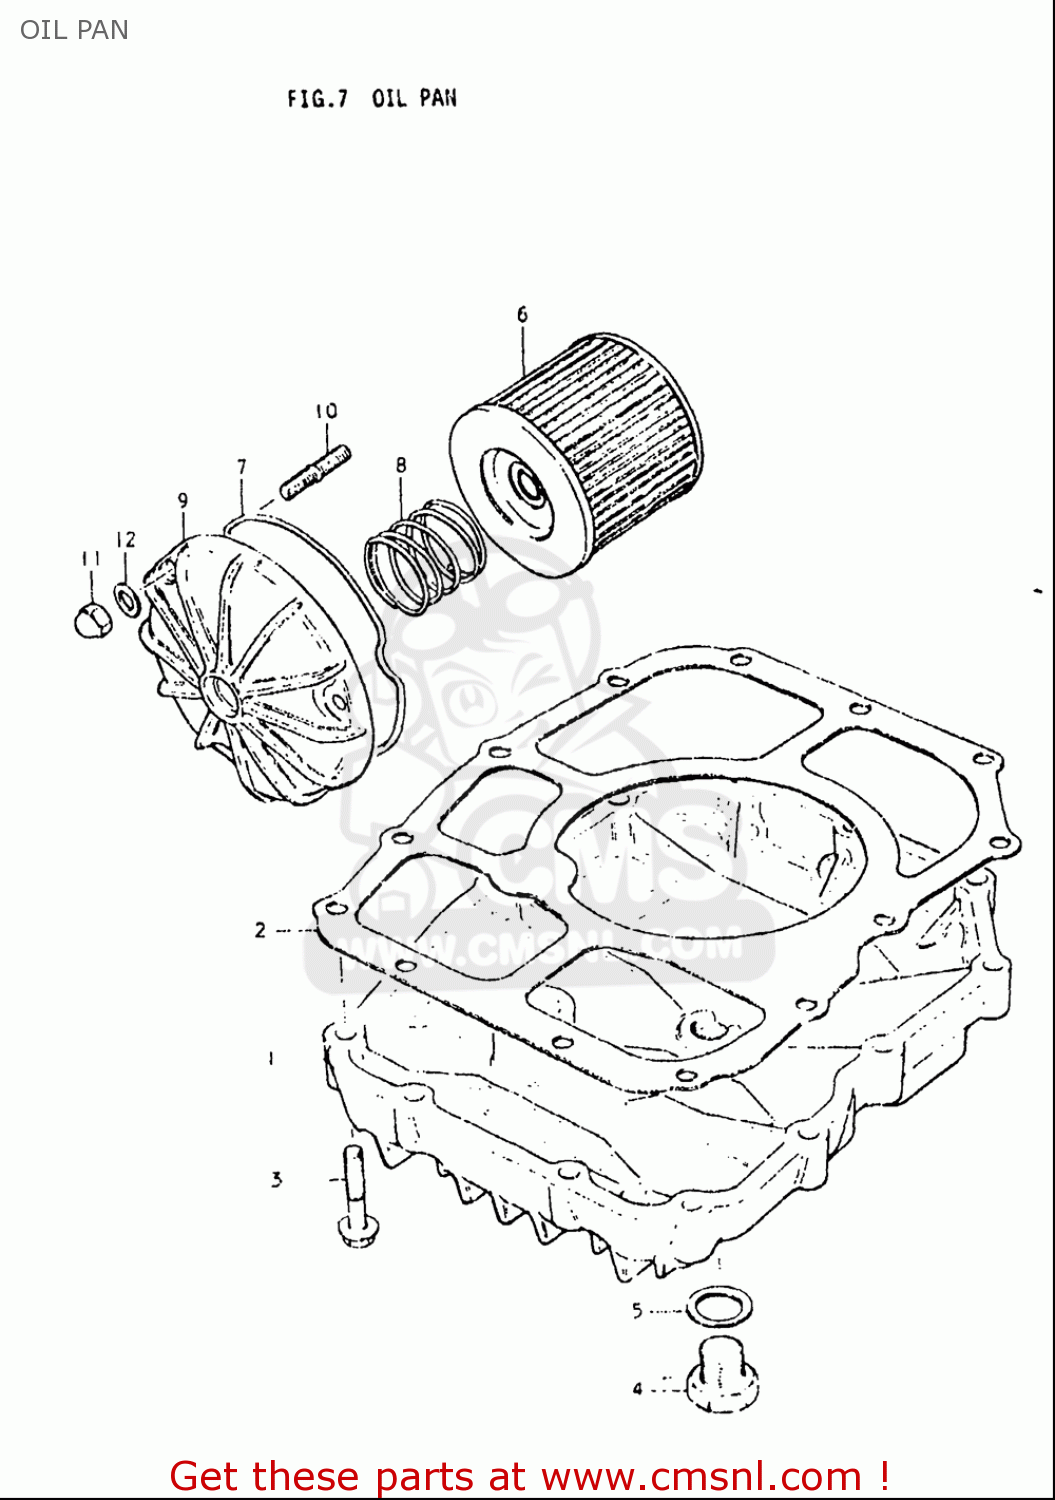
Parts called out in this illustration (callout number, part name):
1	PAN,OIL
2	GASKET,OIL PAN (NAS)
3	BOLT
4	PLUG(MAGNETO)
5	GASKET(14X19.2X2) (NAS)
6	FILTER ASSY,ENGINE OIL
7	O RING,OIL FILTER CHAMBER CAP
8	SPRING
10	BOLT,STUD
11	NUT
12	WASHER
